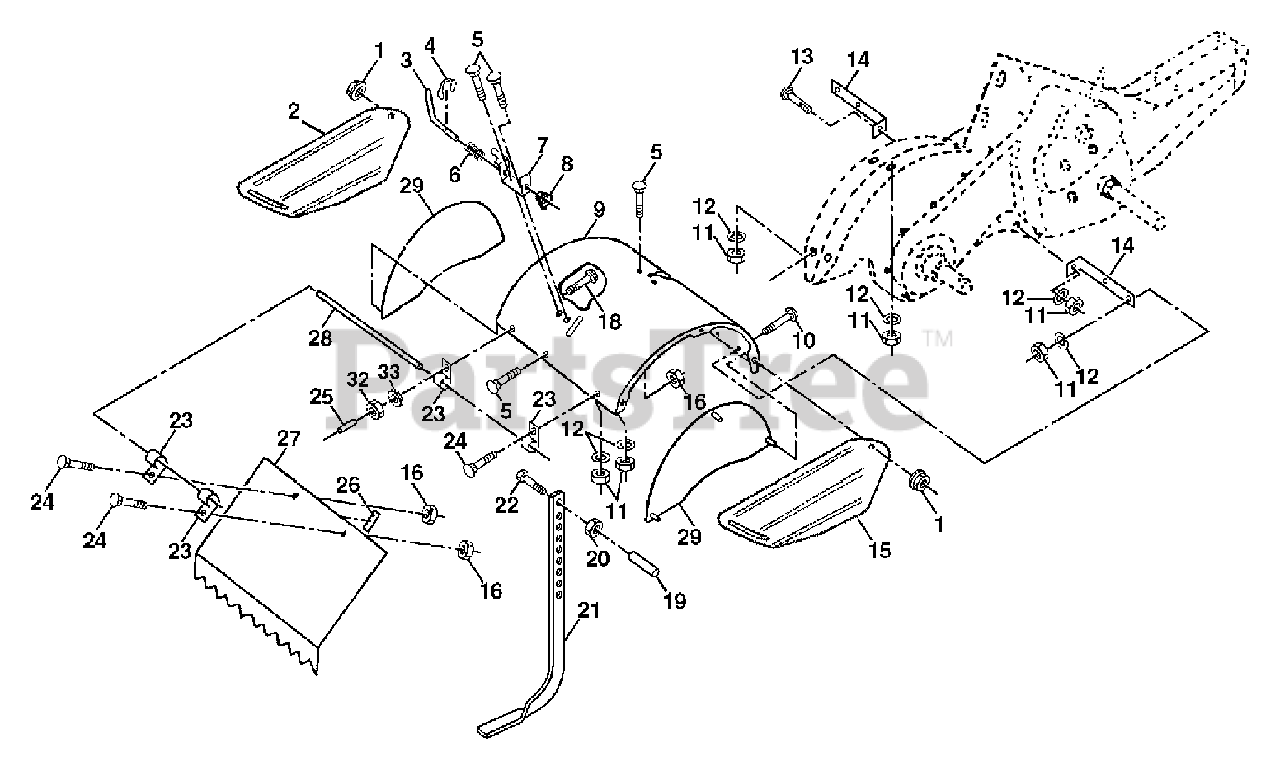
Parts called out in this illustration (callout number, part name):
1	Nut, Lock Hex Flange 5/16-18
2	Shield, Side, Outer L.H.
3	Pin, Stake, Depth
4	Ring, Klip
5	Bolt, Rdhd Sqnk 5/16-18 x 3/4
7	Bracket, Latch
8	Spring, Depth Stake
9	Shield, Tine
10	Bolt, Carriage 5/16-18 UNC x 1
11	Nut, Hex 5/16-18
12	Washer, Lock 5/16
13	Bolt, Carriage 5/16-18 x 1-1/4
14	Bracket, Shield Tine
15	Shield, Side, Outer R.H.
16	Nut, Hex Flange 1/4-20 UNC
18	Bolt, Carriage 1/4-20 x 1-1/4 Gr.
20	Nut, Hex 3/8-16
21	Stake, Depth
22	Bolt, Hex 3/8-16 x 2
24	Bolt, Carriage 1/4-20 x 1/2 Gr. 5
25	Cap, Vinyl
26	Pad, Idler
27	Shield, Leveling
28	Pin, Hinge
29	Shield, Side
30	Locknut, Flange 5/16-18
32	Nut Fin Hex 1/4-20 UNC
33	Washer Lock Hvy Helical 1/4
